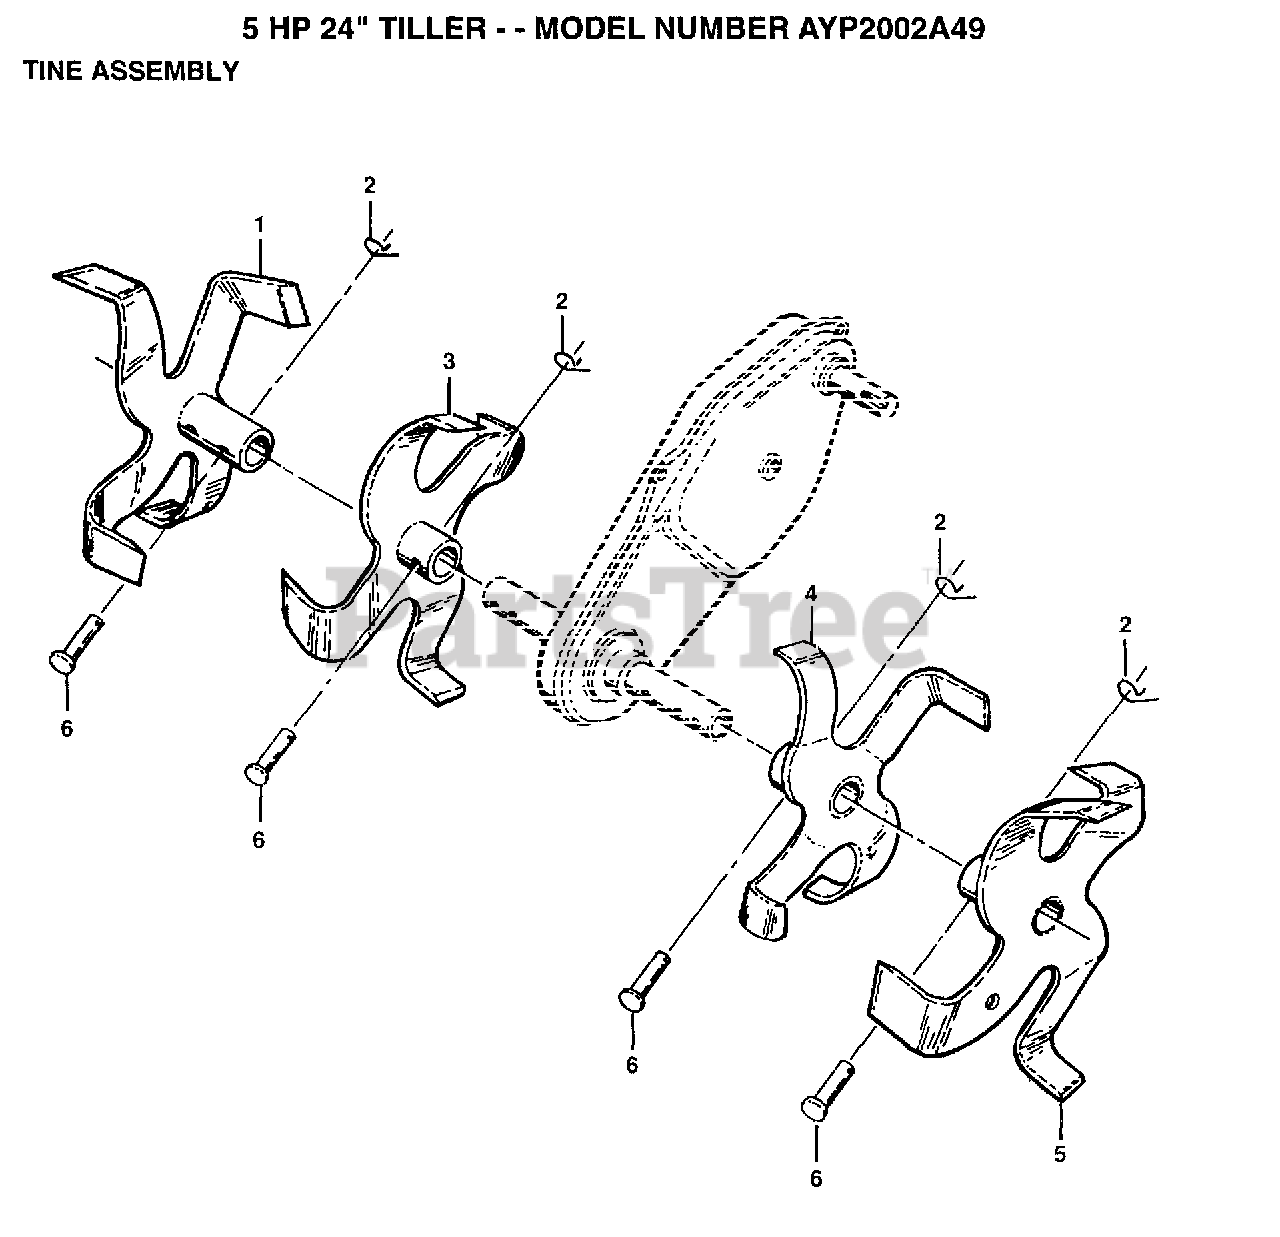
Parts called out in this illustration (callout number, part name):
1	TINE OUTER RH T
2	RETAINER.SPRING
4	TINE.INNER.LH
5	TINE.OUTER.LH.T
6	RIVET.PAN HD.1.75
